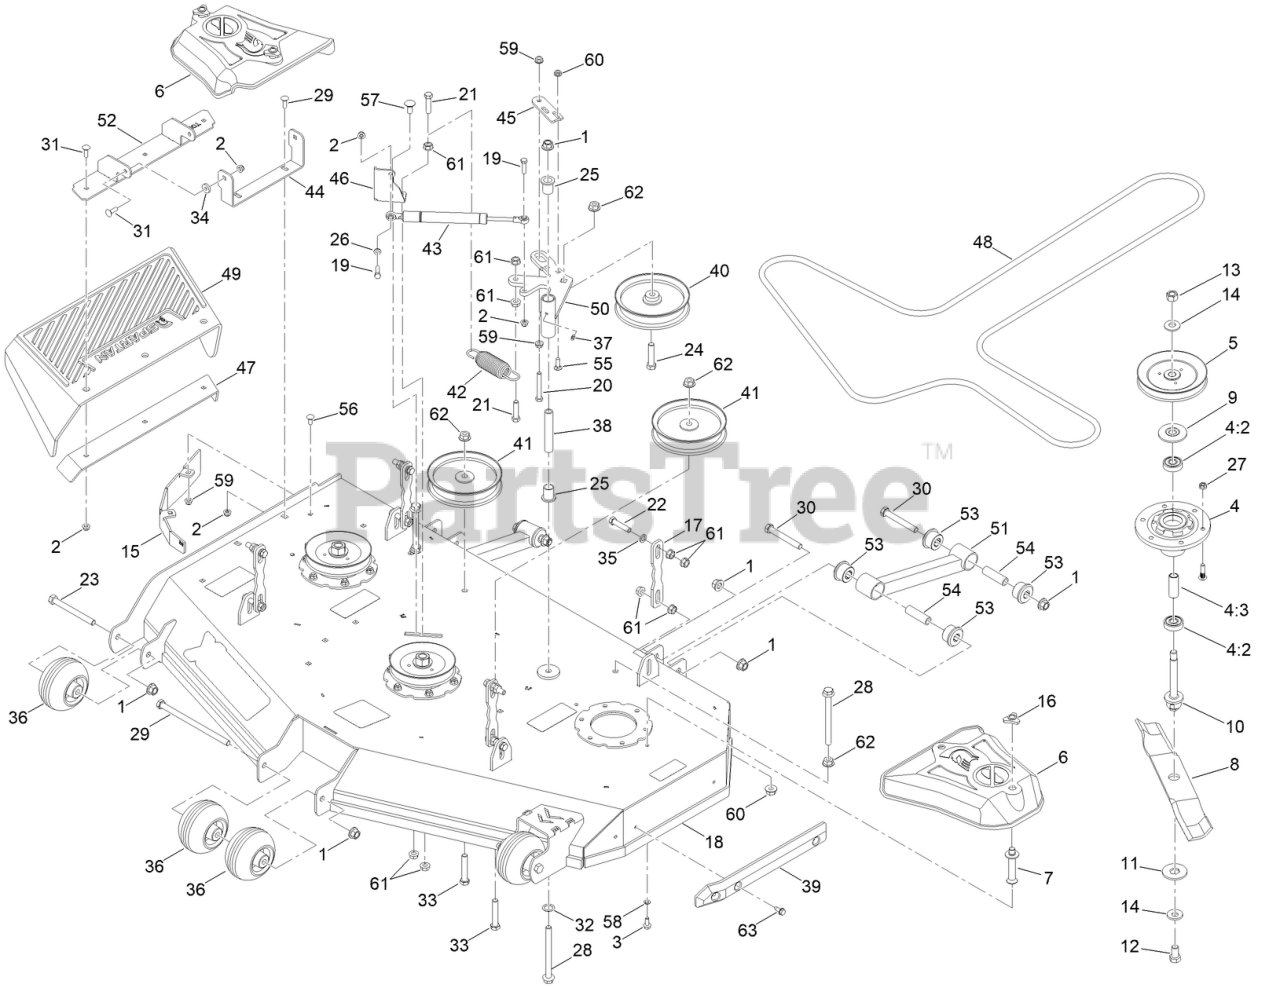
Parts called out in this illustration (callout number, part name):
1	NUT-LOCK
2	NUT-HF, NI
3	SCREW-HHF
4	SPINDLE ASM 5IN DECK
4:2	BEARING
4:3	SPACER, BEARING
5	PULLEY
6	COVER BELT
7	PIN-BELT COVER
8	BLADE-ROTARY
9	GUARD-BEARING TOP 0.673IN
10	SHAFT - SPINDLE
11	WASHER-HEX
12	M16X1.5-30MM C10.9 HEX BOLT
13	M16X1.5 C8.8 HEX NUT
14	M16 SPRING WASHER (39MMOD/ 3.9MM THK)
15	BAFFLE-WIPER 54 PAINTED BLACK
16	NUT-KNOB
17	HANGER-DECK PAINTED BLACK
18	ASM-DECK W/ DECALS
19	SCREW-HH
20	SCREW-HH
21	SCREW-HH
22	SCREW-HH
23	SCREW-HH
24	SCREW-HH
25	3/4IN ID X15/16IN OD X 1-1/8IN FLNG BUSH
26	.312IDX.625ODX.062 THK THRUST BRG OI BRZ
28	1/2-13 X 5-1/2 HEX FLANGE BOLT GR 8 ZY
29	1/2-13 X 8-1/2 HEX C/S GR 2 ZINC YELLOW
30	1/2-13 X 3-3/4 HEX C/S (GR.5) ZC/YEL
31	5/16-18 X 1 CARRIAGE BOLT GR 8 YZ
32	.767IDX1.125ODX.016 THK TRIP WV WASHER
33	1/2-13 X 2-3/4 HEX FLANGE BOLT (GR.8) YZ
34	.312 ID X .875OD X .1875 THK F/W NYL
35	.443 ID X .749 OD X .125 THK NYLON BLACK
36	MWR ANTI-SCALP WHL W/O GREASE FITTING
37	1/4IN DRIVE TYPE GREASE FITTING YZ
38	MWR INNER IDLER SPACER
39	MWR NYLON DECK GUARD
40	6-3/4IN IDLER PULLEY 7/16IN SPACER ASM
41	6-3/4IN IDLER PULLEY 15/16IN SPACER ASSY
42	MWR DECK SPRING
43	IDLER GAS SPRING
44	MWR CHUTE MTG BRKT BLACK
45	DECK IDLER PULLEY BELT RETAINER BRKT
46	DECK BELT IDLER DAMPER MTG BRKT BLACK
47	MWR DECK CHUTE HINGE BACKER BRKT
48	54 DECK BELT
49	RZ MWR RUBBER DISCHARGE CHUTE
50	MWR DECK IDLER PULLEY ARM ASSY BLACK
51	RZ MWR DECK STABLZR ASSY
52	MWR DECK CHUTE HINGE ASSY
53	RED A80 SUSP BUSHING
54	UTV A-ARM BUSHING SLEEVE
55	BOLT-CARR
56	3/8-16 X 1 CARRIAGE BOLT YZ GR.8
57	SCREW-CARR
58	WASHER-LOCK
59	3/8-16 HEX FLANGE NUT W/SERR ZINC YELLOW
61	NUT-HF
62	NUT-HHF
63	SCREW-HWH, THREAD CUT
